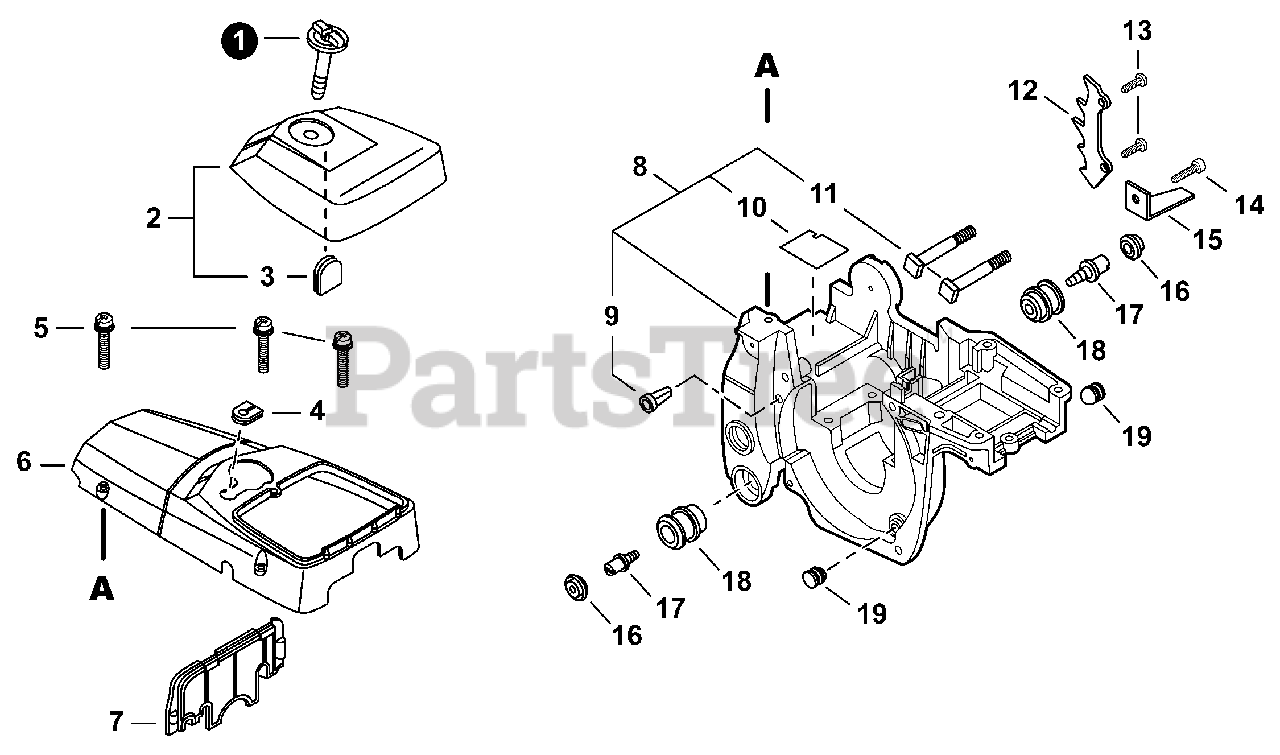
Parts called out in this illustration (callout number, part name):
1	THUMBSCREW
2	COVER ASSY, AIR FILTER
4	GROMMET, HT
5	SCREW 5×20
6	COVER, ENGINE
7	PLATE, INSULATOR
8	COVER ASSY, ENGINE
9	VENT ASSY
10	SHIELD, HEAT
11	STUD, GUIDE BAR 8
12	SPIKE, BUMPER
13	BOLT, TAPPING 5×20
14	BOLT, TAPPING 5×16
15	CHAIN CATCHER
16	CAP, CUSHION
18	CUSHION 5
19	CUSHION
